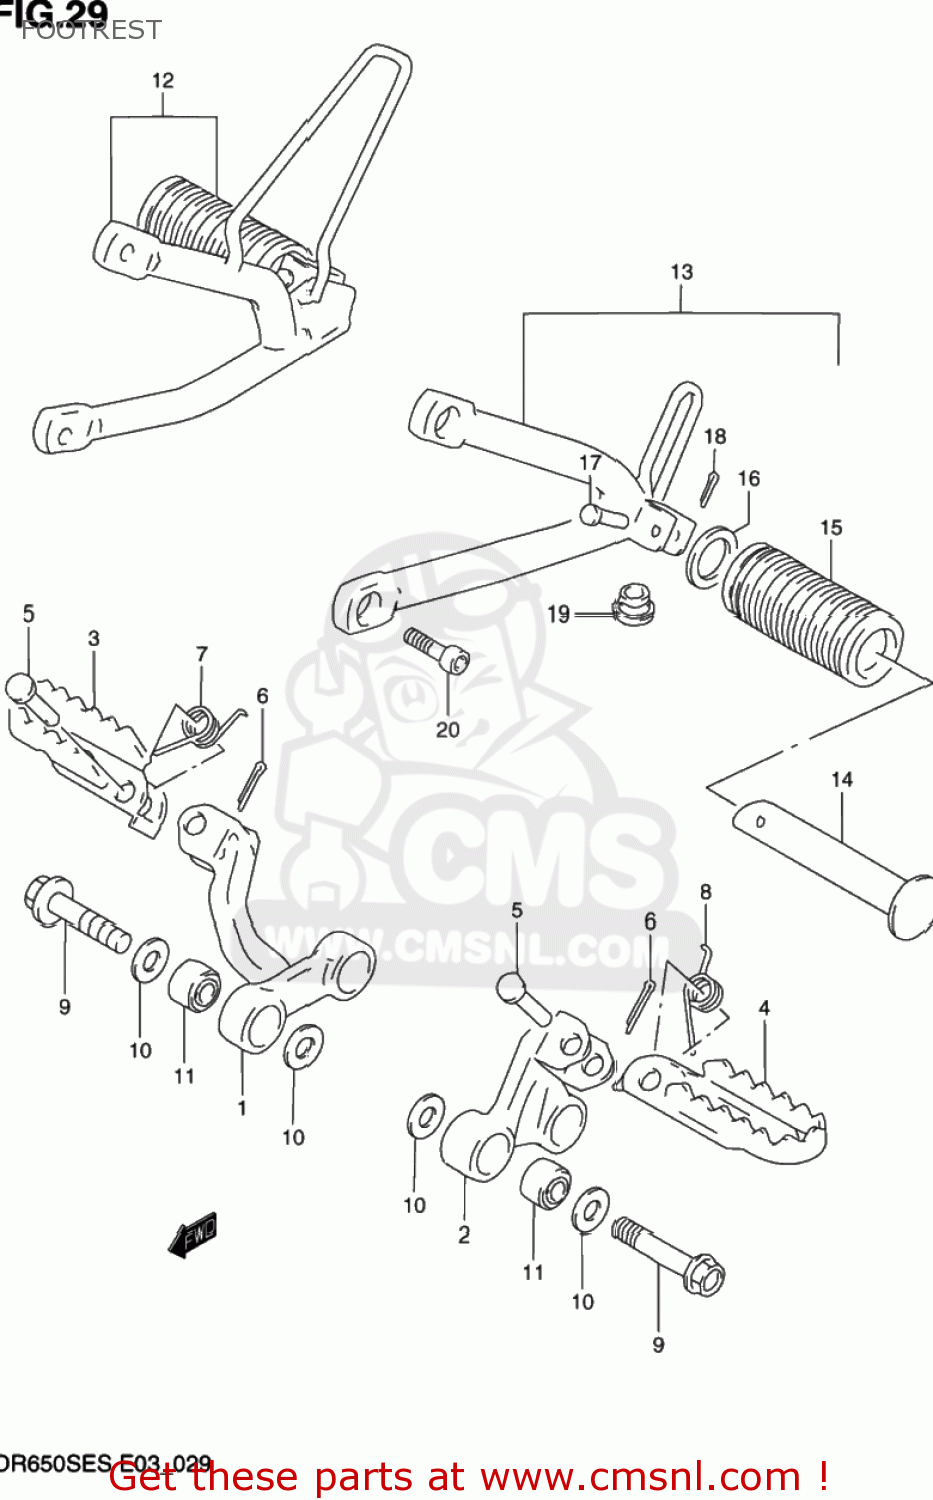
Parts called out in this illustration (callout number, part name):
1	BAR,FR FOOTREST,R
2	BRACKET,FR FOOTREST,L
3	FOOTREST,FR,R
4	FOOTREST,FR,L
5	PIN
6	PIN 20X20
7	SPRING
8	SPRING
9	BOLT(10X50)
10	WASHER
11	BUSH(10.2X25X19)
12	FOOTREST ASSEMBLY,PILLION
13	FOOTREST ASSEMBLY,PILLION
14	BAR,FOOTREST RUBBER
15	RUBBER,PILLION FOOTREST
16	WASHER (19.5X32X2)
17	PIN
18	PIN
19	CAP(OD:19)
20	BOLT
